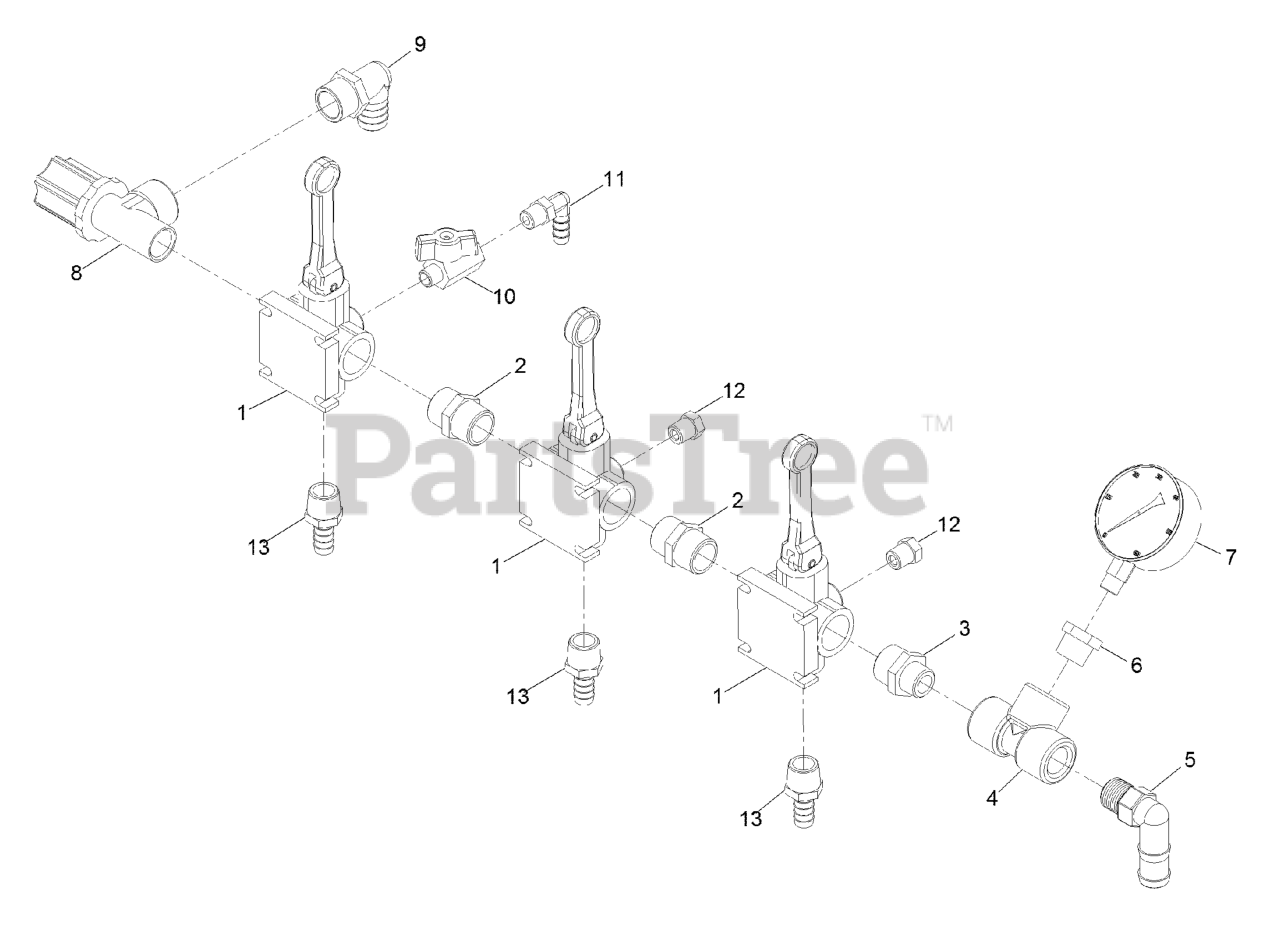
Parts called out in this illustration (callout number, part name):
1	VALVE-DIRECTO
2	FITTING-NIPPLE
3	FITTING-NIPPLE
5	ELBOW-90
6	FITTING-REDUCER
7	GAUGE
8	VALVE-THROTTLE
9	FITTING-ELBOW, 90
10	VALVE-CHROME, 1/4
11	FITTING-ELBOW, 90
12	PLUG-VALVE
13	FITTING-HOSEBARB
